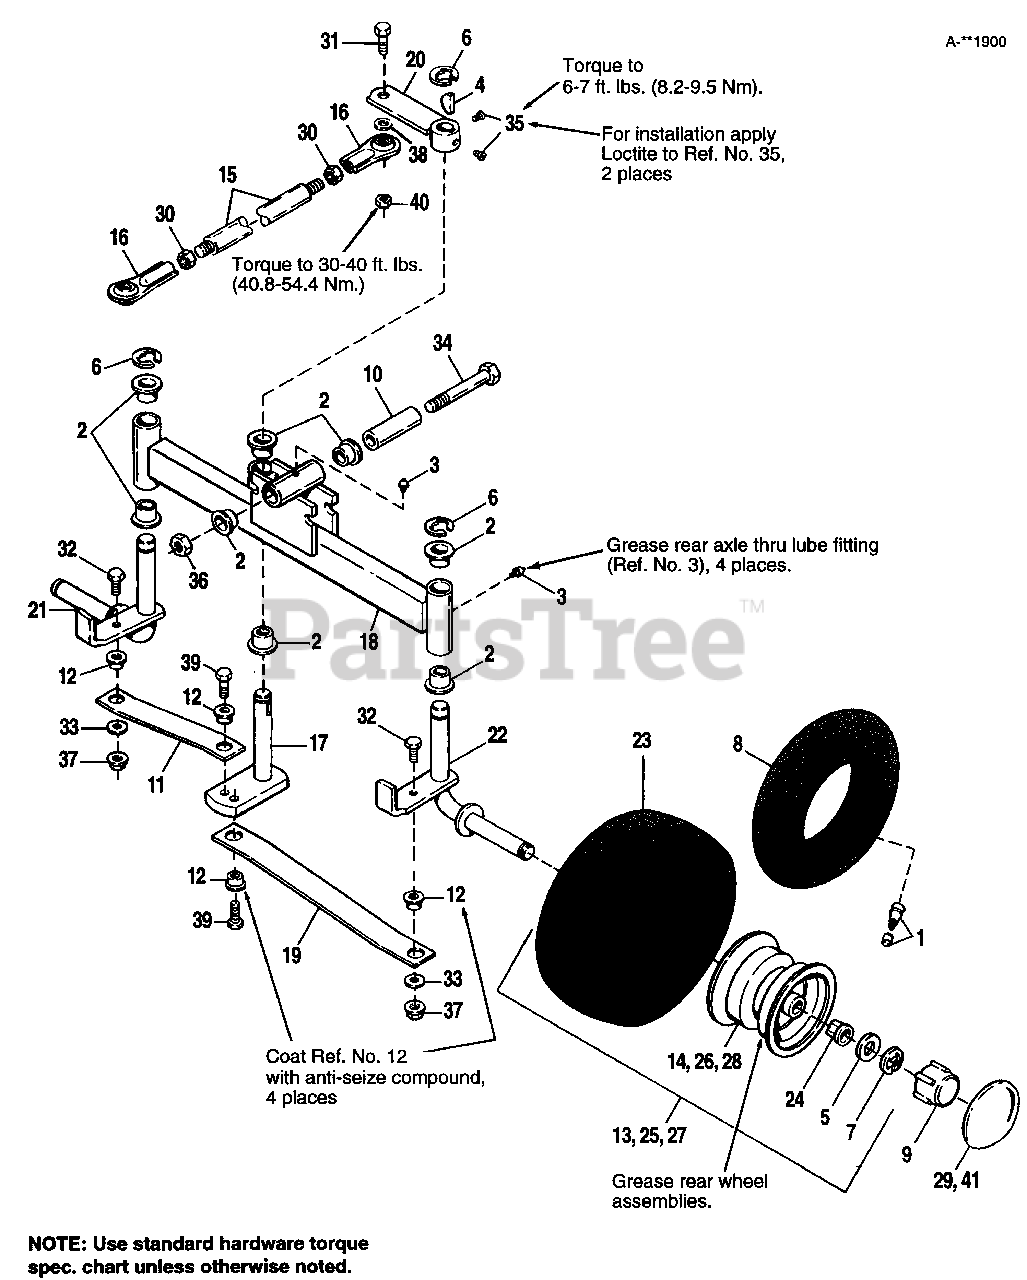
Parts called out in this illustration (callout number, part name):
1	VALVE STEM & CAP
2	BEARING, Nylon
3	LUBE FITTING
4	KEY, Hi Pro, 3/16 x 5/8
5	WASHER, 3/4
7	RING, Retaining
8	TUBE (Service only, see note below)
9	CAP, Threaded
10	TUBE, Pivot Support
13	REAR WHEEL & TIRE ASSY., Silver, 13-1/2" wide x 6" dia. (Incl. Ref. Nos. 1, 4 & 23)
14	REAR WHEEL ASSY., Silver, 13-1/2" wide x 6" dia. (Incl. Qty. 2 of Ref. No. 24)
16	ROD END, Ball Joint
17	STEERING ARM ASSY
18	REAR AXLE ASSY.
19	ROD, Tie
20	STEERING ARM ASSY.
21	SPINDLE ASSY., RH
22	SPINDLE ASSY., LH
23	TIRE, Dico, 13 x 5.00-6
24	BEARING
25	REAR WHEEL & TIRE ASSY., White, 13-1/2" wide x 6" dia. (Incl. Ref. Nos. 1, 8, 23 & 26)
26	REAR WHEEL ASSY., White, 13-1/2" wide x 6" dia. (Incl. Qty. 2 of Ref. No. 24)
27	REAR WHEEL & TIRE ASSY., Metallic Gray, 13-1/2" wide x 6" dia. (Incl. Ref. Nos. 1, 8, 23 & 28)
28	REAR WHEEL ASSY., Metallic Gray, 13-1/2" wide x 6" dia. (Incl. Qty. 2 of Ref. No. 24)
29	HUB CAP, Black, Smooth, 5-3/4 diameter
30	NUT, Jam, 1/2-20
31	CAPSCREW, Hex Hd., 1/2-13 x 1-1/2
32	CAPSCREW, Hex, 3/8-16 x 1-1/4
33	WASHER, 3/8
34	CAPSCREW, 1/2-13 x 4
35	SETSCREW, Cup Pt., 1/4-20 x 5/16
36	NUT, ESNA, Lock, 1/2-13
37	NUT, Centerlock, 3/8-16
38	WASHER, 1/2
39	CAPSCREW, Whizlock, 3/8-16 x 7/8
40	NUT, Lock, ESNA, 1/2-13 (Thin)
41	HUB CAP, Black, Scalloped, 5-3/4 diameter
